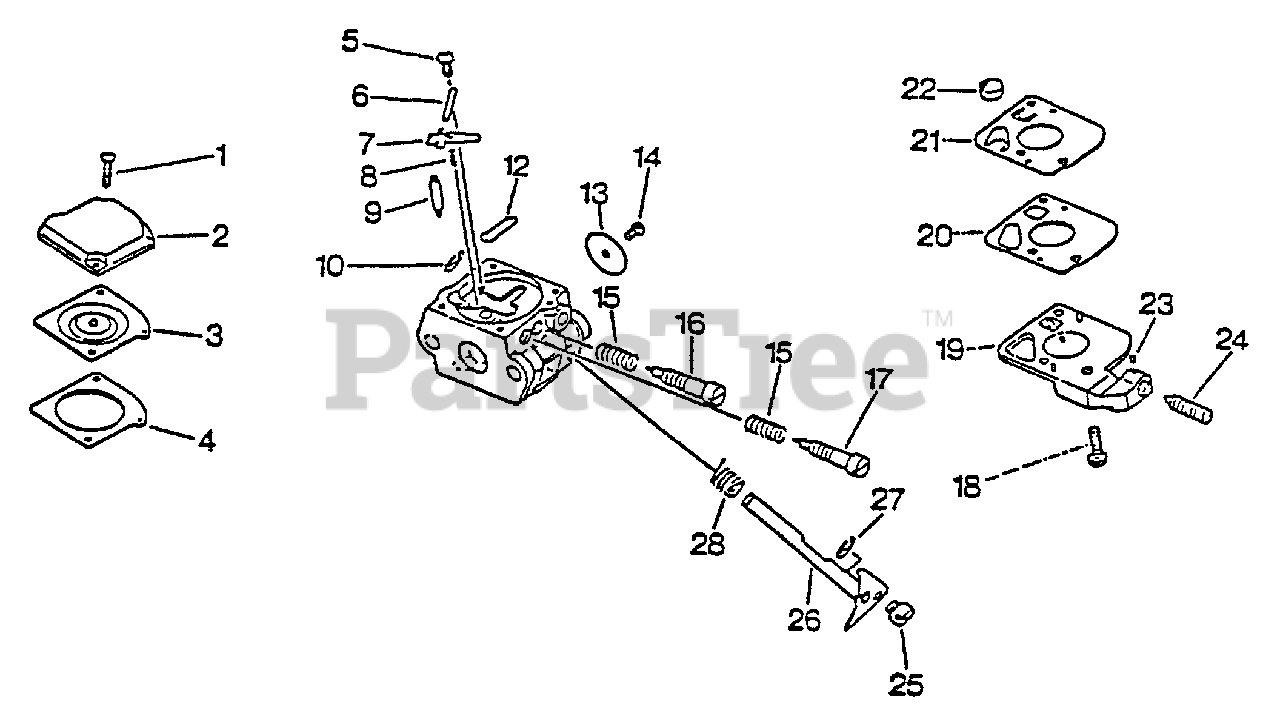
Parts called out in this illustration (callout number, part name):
2	COVER, METERING
3	DIAPHRAGM
4	GASKET, DIAPHRAGM
5	SCREW, METERING LEVER PIN
6	PIN, METERING LEVER
7	LEVER, METERING
8	SPRING
9	VALVE, NEEDLE
10	RING, RETAINING
11	NOZZLE, CHECK VALVE
12	PLUG, WELCH
13	VALVE, THROTTLE
14	SCREW
16	NEEDLE - HIGH SPEED
17	NEEDLE - LOW SPEED
18	SCREW, PUMP COVER
19	BASE, PURGE
20	GASKET, PUMP
21	DIAPHRAGM, PUMP
22	STRAINER
23	PIECE, FRICTION
24	SCREW, IDLE ADJUST
26	SHAFT, THROTTLE
27	RING, RETAINING
28	SPRING, RETURN
